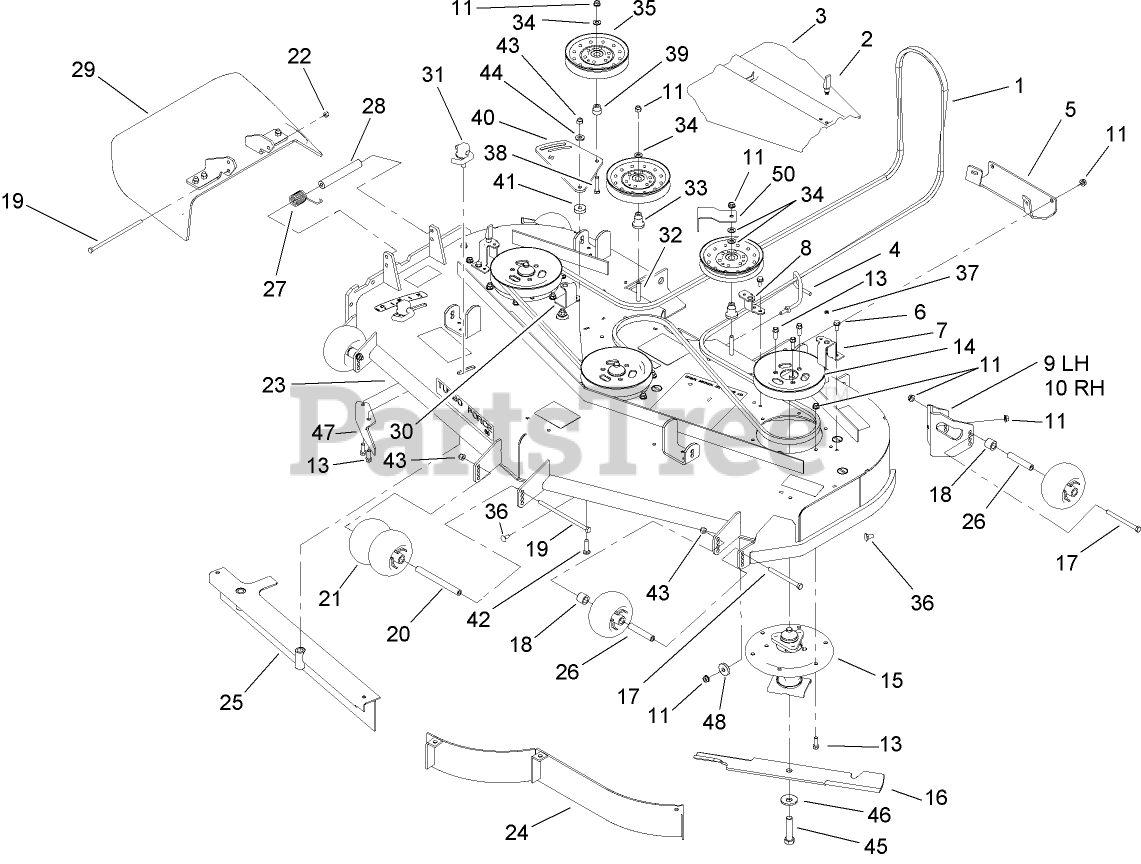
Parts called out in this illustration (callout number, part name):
2	LATCH-SWELL
3	COVER-BELT
4	GUIDE-BELT
5	Plate-Skid
6	SCREW-HWHTF
7	BRACKET-COVER
8	BRACKET-COVER, TALL
9	MOUNT-WHEEL, LH
10	MOUNT-WHEEL, RH
11	NUT-HHF, WHIZ
13	SCREW-HWH
14	Pulley
15	Spindle ASM
16	BLADE-HI FLOW
17	SCREW-HH
18	TUBE-SPACER
19	SCREW-HH
20	SPACER-WHEEL
21	ROLLER-SCALP, ANTI
22	NUT-LOCK, NI
23	DECK ASM
26	TUBE-SPANNER
27	SPRING-TORSION
28	SPACER
29	RUBBER DEFLECTOR ASM
30	BRACKET-COVER
31	LEVER ASM
32	SCREW-HH
33	MOUNT-PULLEY
34	WASHER-FLAT
35	Idler-Flat
36	SCREW-CARR
37	WASHER
38	SCREW-HH
39	BUSHING-IDLER
40	Plate-Idler
41	Spacer
42	SCREW-CARR
43	NUT-LOCK, NI
44	WASHER-BELLEVILLE
45	Screw-Cap
46	Washer-Blade Bolt, Heavy
47	BAFFLE-DISCHARGE
48	WASHER
50	GUIDE-BELT
99	BLADE-MID FLOW, 20.5 INCH
99	BLADE-RECYCLER, 20.5 INCH
